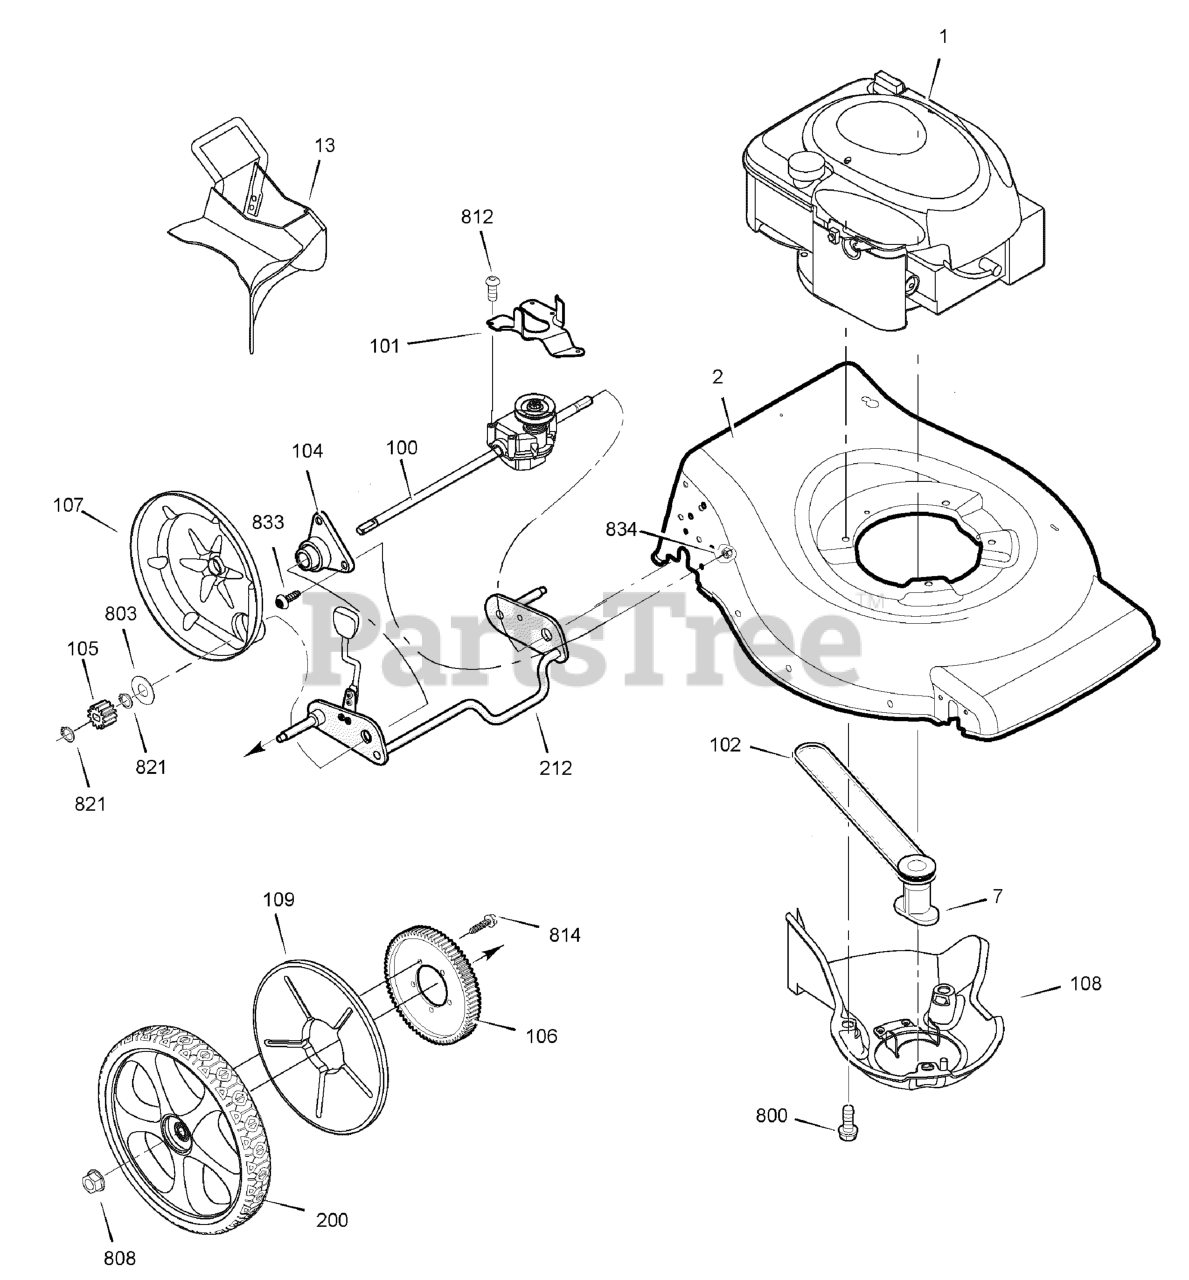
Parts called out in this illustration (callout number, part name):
1	* ENGINE
2	MOWER HOUSING
7	BLADE ADAPTER ASSEMBLY
13	MULCH PLUG
100	TRANSMISSION
101	BELT GUIDE, Transmission
102	V-BELT
104	SLEEVE ASSEMBLY, Rear Axle
105	GEAR, Pinion
106	GEAR, Drive
107	DUST COVER
108	BELT COVER ASSEMBLY
109	COVER, Wheel
200	WHEEL, Rear
212	CROSSBAR ASSEMBLY, Rear
800	SCREW, Hex Head, 3/8-16 x 1
803	WASHER, Thrust
808	NUT, Flange, 3/8-16
812	SCREW, #10 x 1
814	SCREW, 1/4-15 x 3/4
821	RING, External Retaining
833	SCREW, Torx, 1/4-20 x 5/8
834	NUT, Flange Lock, 1/4-20
